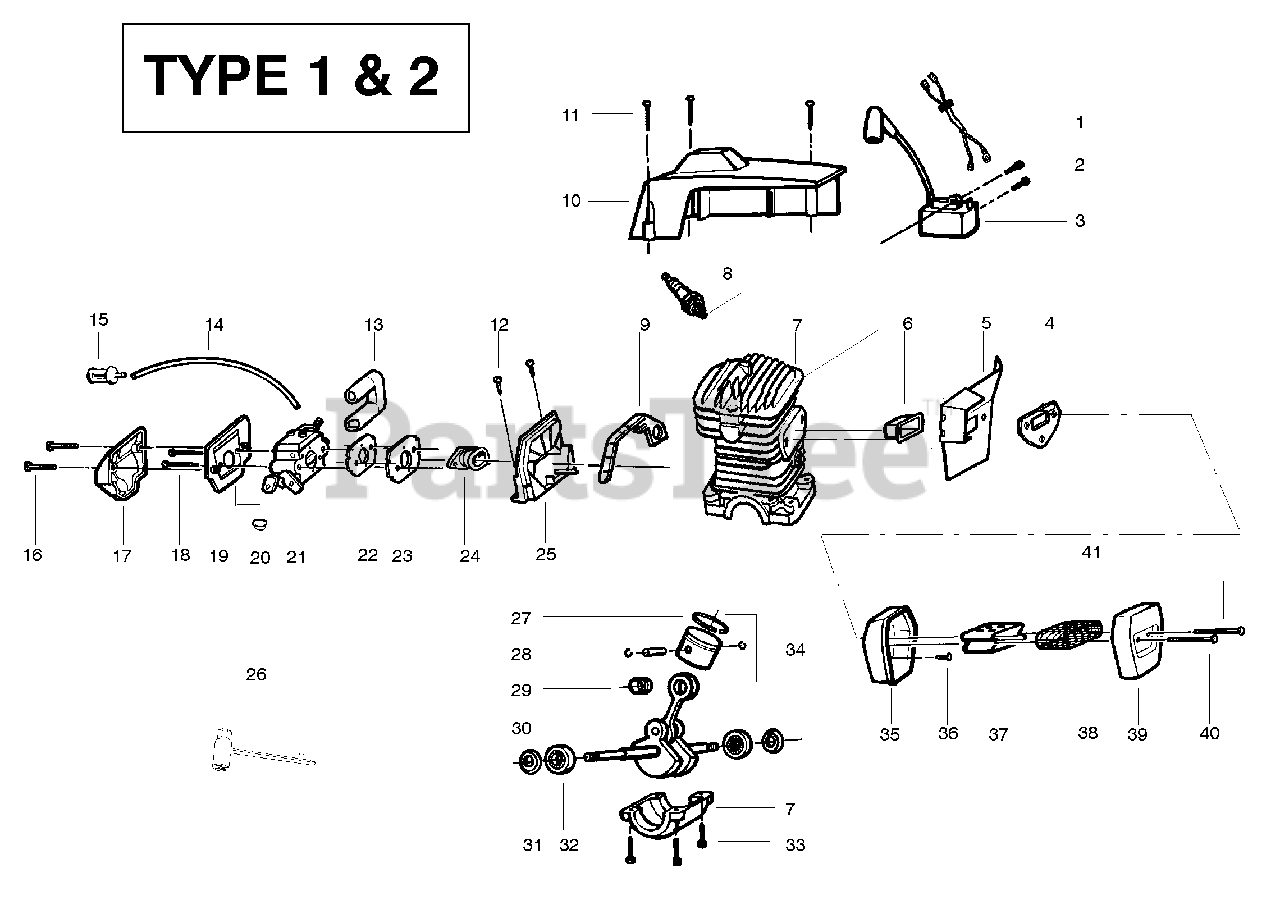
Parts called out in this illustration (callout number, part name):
1	Switch Wire Ass'y.
3	Ignition Module
4	Muffler Gasket
5	Muffler Plate
6	Heat Insulator
7	C'case&Cylinder Assy
8	Spark Plug (RCJ-7Y)
9	Super Clean Seal
10	Cylinder Shield Kit
13	Carb. Grommet
14	Kit - Line Carb / Purge
15	Fuel Pick-up Assy.
17	Air Filter (Top)
19	Air Filter (Bottom)
21	Carburetor WT-529
21	Carburetor WT-285 , WT-289
22	Carburetor Gasket
23	Carburetor Plate
24	Intake Boot
25	Carb. Adaptor
28	Piston Pin Retainer
29	Piston Pin Bearing
30	C'shaft & Rod Ass'y.
31	C'shaft Seal
32	C'shaft Bearing
34	Piston Kit
39	Muffler Cover
41	Muffler Kit
